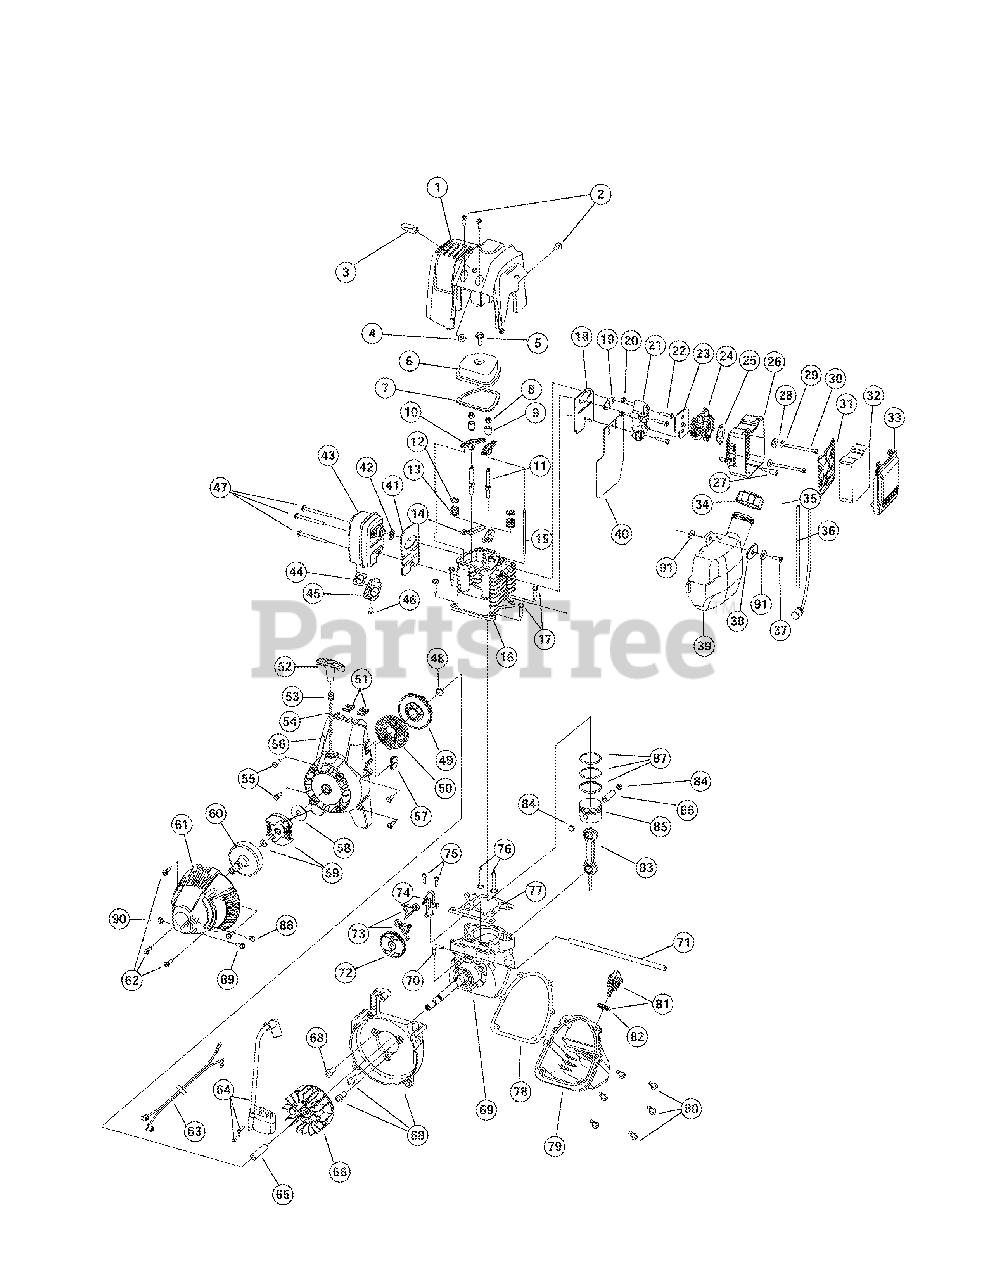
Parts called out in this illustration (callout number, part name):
1	Engine Cover
2	Engine Cover Screws
3	Starter Rope Eyelet
5	Valve Cover Screw
6	Valve Cover
7	Valve Cover Gasket
8	Rocker Adjustment Nut
9	Rocker Arm Pivot
11	Rocker Arm Stud
12	Valve Spring Retainer
13	Valve Spring
14	Push Rod Guide
15	Push Rod
16	Cylinder Assembly (Includes 11-14)
17	Cylinder Screw
18	Intake Baffle
19	Carburetor Mount Gasket
20	Nut
21	Carburetor Mount (Includes 20)
22	Carburetor Mount Screw
23	Carburetor Gasket
24	Carburetor with Primer
25	Air Filter Gasket
26	Air Filter Cover Assembly (Includes 27, 28, 31-33)
27	Breather Tube Assembly
28	Grommet Washer
30	Air Filter Mounting Screw
31	Air Filter Plate
33	Air Filter Cover
35	Fuel Return Line
36	Fuel Pick-Up Line with Filter
38	Bushing
39	Fuel Tank Assembly (Includes 34-36)
40	Fuel Tank Shield
41	Muffler Baffle
42	Muffler Gasket
43	Muffler (Includes 42, 44-46)
44	Spark Arrestor Screen
45	Screen Cover
47	Muffler Mounting Screw
49	Recoil Pulley
50	Recoil Spring
52	Pull Handle
55	Starter Housing Screw
56	Starter Assembly
57	Wire Grommet
58	Clutch Washer
59	Clutch with Washer
60	Clutch Drum
61	Clutch Cover
62	Clutch Cover Screw
64	Ignition Module with Screws
66	Flywheel
68	Shroud Assembly with Screws (Includes 67)
69	Crankcase Assembly (Includes 70 & 71)
70	90 degree Elbow
71	Breather Hose
73	Cam Follower
74	Cam Bracket
75	Cam Bracket Screw
76	Valves, Intake and Exhaust
77	Cylinder Gasket
78	Oil Pan Gasket
79	Oil Pan (Includes 78 & 80)
80	Oil Pan Screw
81	Dipstick Assembly (Includes 82)
83	Connecting Rod
84	Wrist Pin Button
85	Piston
87	Piston Ring Set
88	Anit-Rotation Screw
89	Screw
